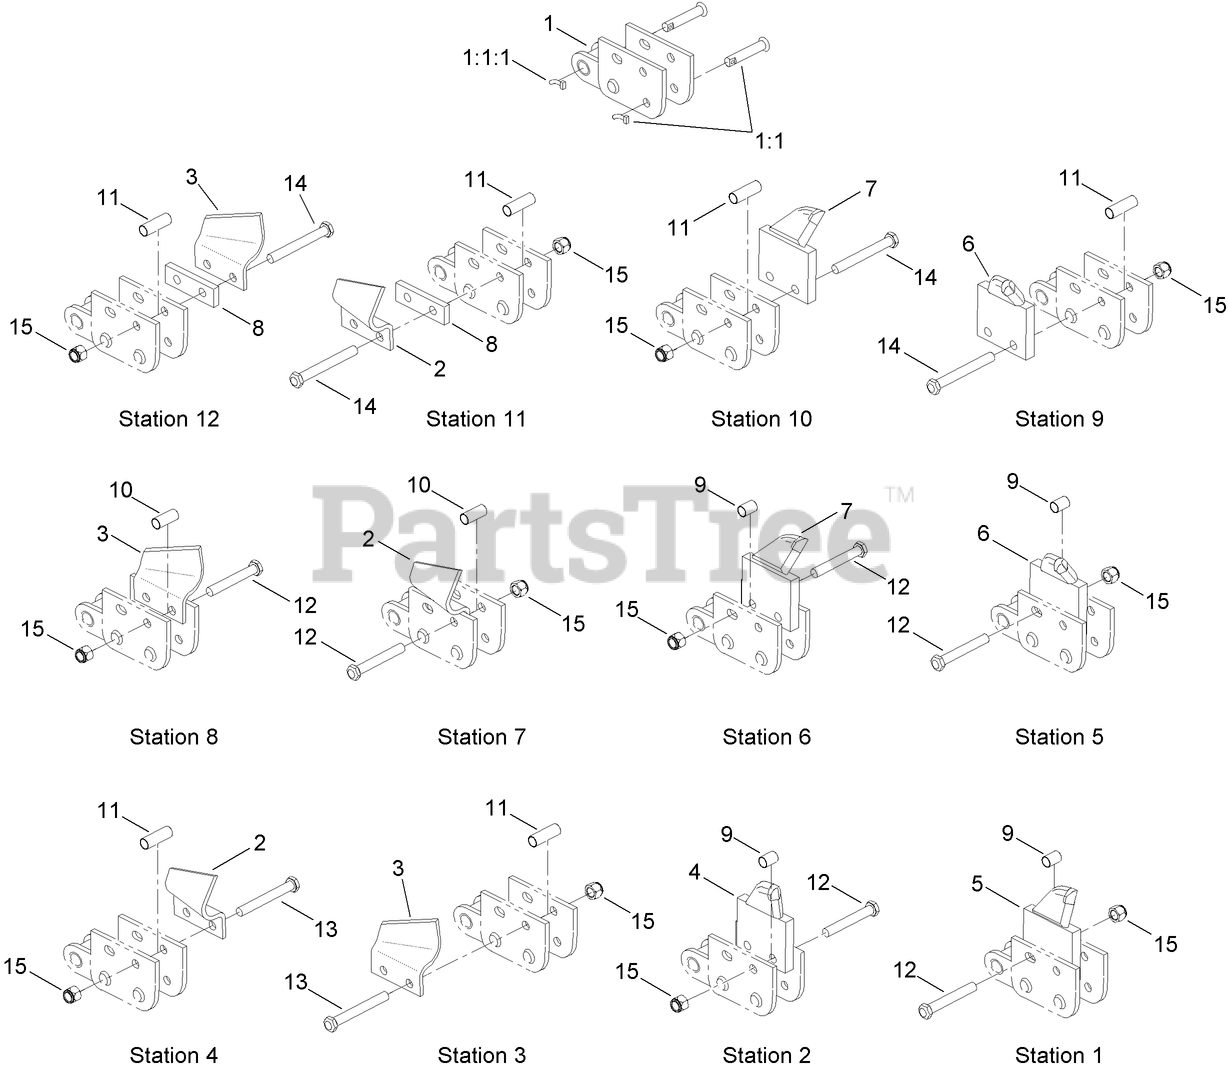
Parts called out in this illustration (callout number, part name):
1	CHAIN REPAIR LINK ASM
1:1	NOTCHED PIN AND KEEPER ASM
1:1:1	PIN-KEEPER
2	CUTTER-CUP, RH
3	CUTTER-CUP, LH
4	TOOTH-TERMINATOR, RH CENTER
5	TOOTH-TERMINATOR, LH CENTER
6	TOOTH-TERMINATOR, RH
7	TOOTH-TERMINATOR, LH
8	SPACER-FLAT
9	SPACER-TUBE, INSIDE ADAPTER
10	SPACER-TUBE, INSIDE CUP
11	SPACER-TUBE, OUTSIDE MOUNT
12	BOLT-HH
13	BOLT-HH
14	BOLT-HH
15	NUT-LOCK
